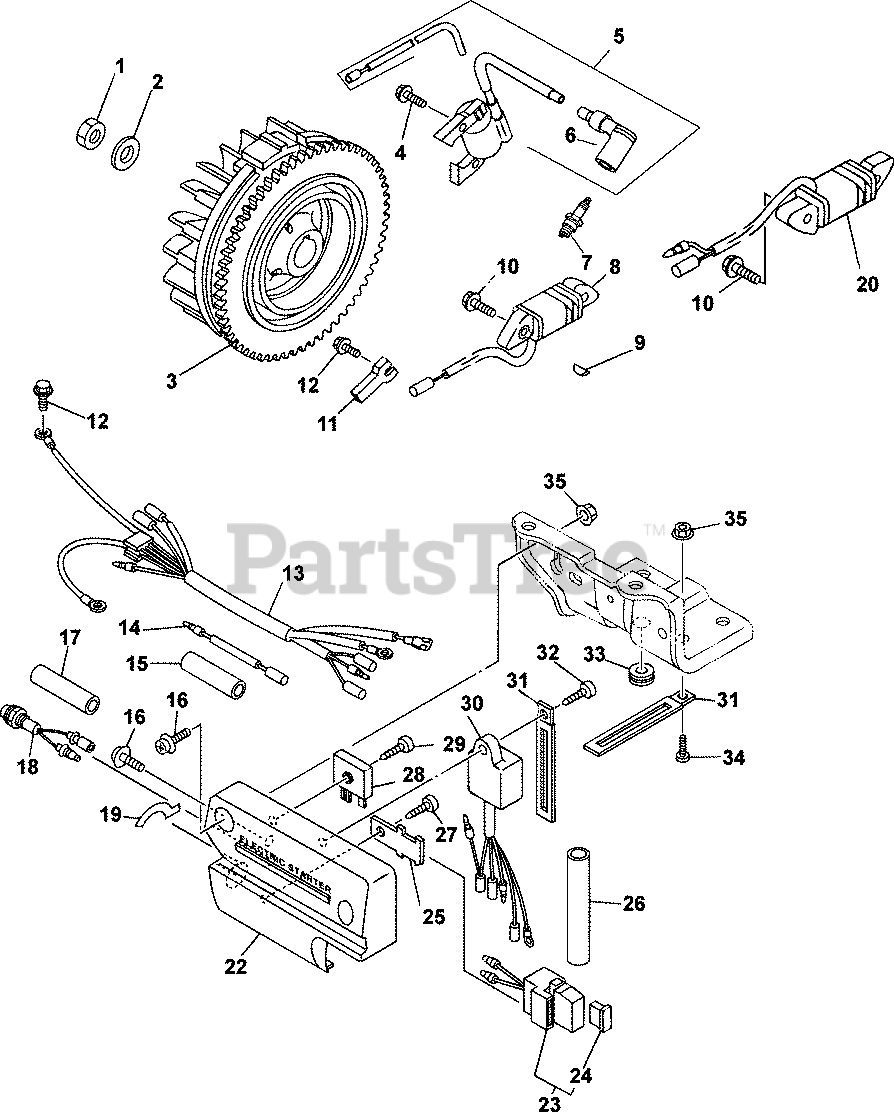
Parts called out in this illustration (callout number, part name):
3	FLYWHEEL - DISCONTINUED
5	KIT, IGNIT MODULE (600 SERIES)
6	CAP ASSEMBLY
7	SPARK PLUG
8	STATOR, FOR 600 SERIES SPECS
9	KEY, WOODRUFF
13	LEAD-DISCONTINUED
15	SLEEVE, WIRING
16	SCREW, BIND
17	SLEEVE, WIRE
18	OIL LIGHT
19	DECAL, IGNITION
22	PANEL, 600 SERIES
23	FUSE HOLDER
26	SLEEVE, WIRE
27	SCREW, TAPPING
28	RECTIFIER / DIODE
30	OIL SWITCH ASSEMBLY -USE 63 099 03-S
34	SCREW, STOP SWITCH
35	NUT, STOP SWITCH
